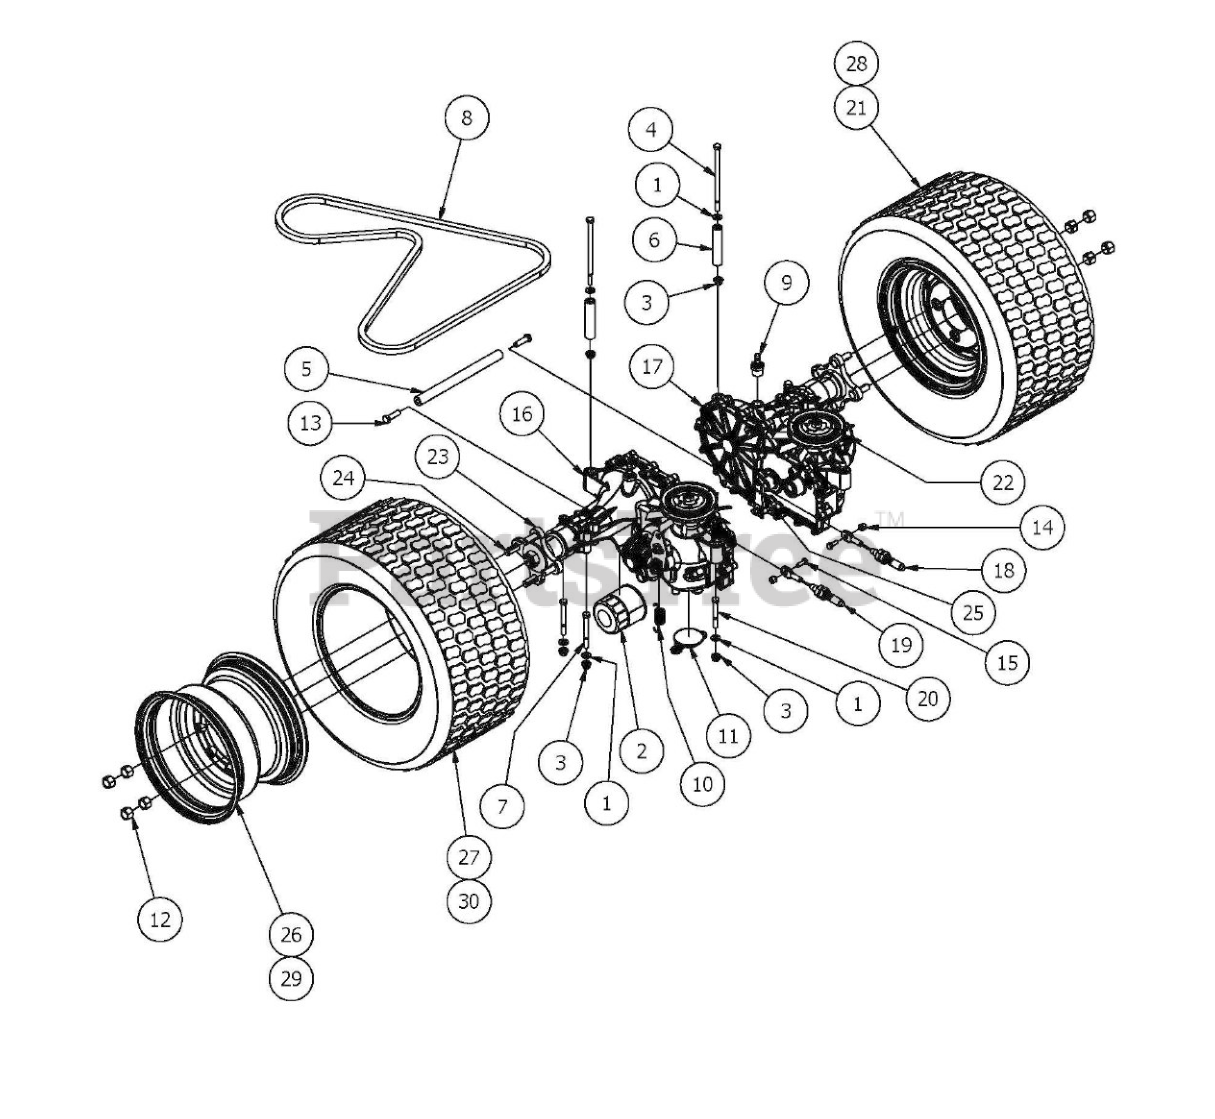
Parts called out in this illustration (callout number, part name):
1	5/16" Flat Washer
3	5/16-18 Nylon Flange Nut
4	5/16" x 6" Bolt
5	2017 Transaxle Spacer-ZT
6	2017 Transaxle Spacer
7	5/16" x 3" Hex Bolt
9	45 degree fitting
10	Transaxle Spring
11	ZT Transaxle Charge Plate/With O'Ring
12	Acorn Lug Nut
13	3/8" x2" Hex Bolt
14	1/4-20 Nylon Insert flange Nut
15	1/4" x 3/4" Hex Bolt
16	Right ZT Transaxle
17	left ZT Transaxle
18	Brake Cable
19	Brake Cable
20	5/16" x 2 1/2" Bolt
21	ZT Tire and Rim Assembly 22 x 11 - 10
22	Fan/Pulley Kit for ZT
23	Transaxle Hub
24	Transaxle Wheel Studs
25	Transaxle Brake Lever
26	ZT Black Wheel Only
27	ZT Tire Only 22x-11-10
28	48" ZT Only Tire 22x10-10 Tire and Wheel
29	48" ZT Only 10" Black Wheel
30	48" ZT Only 22x10-10 Tire
